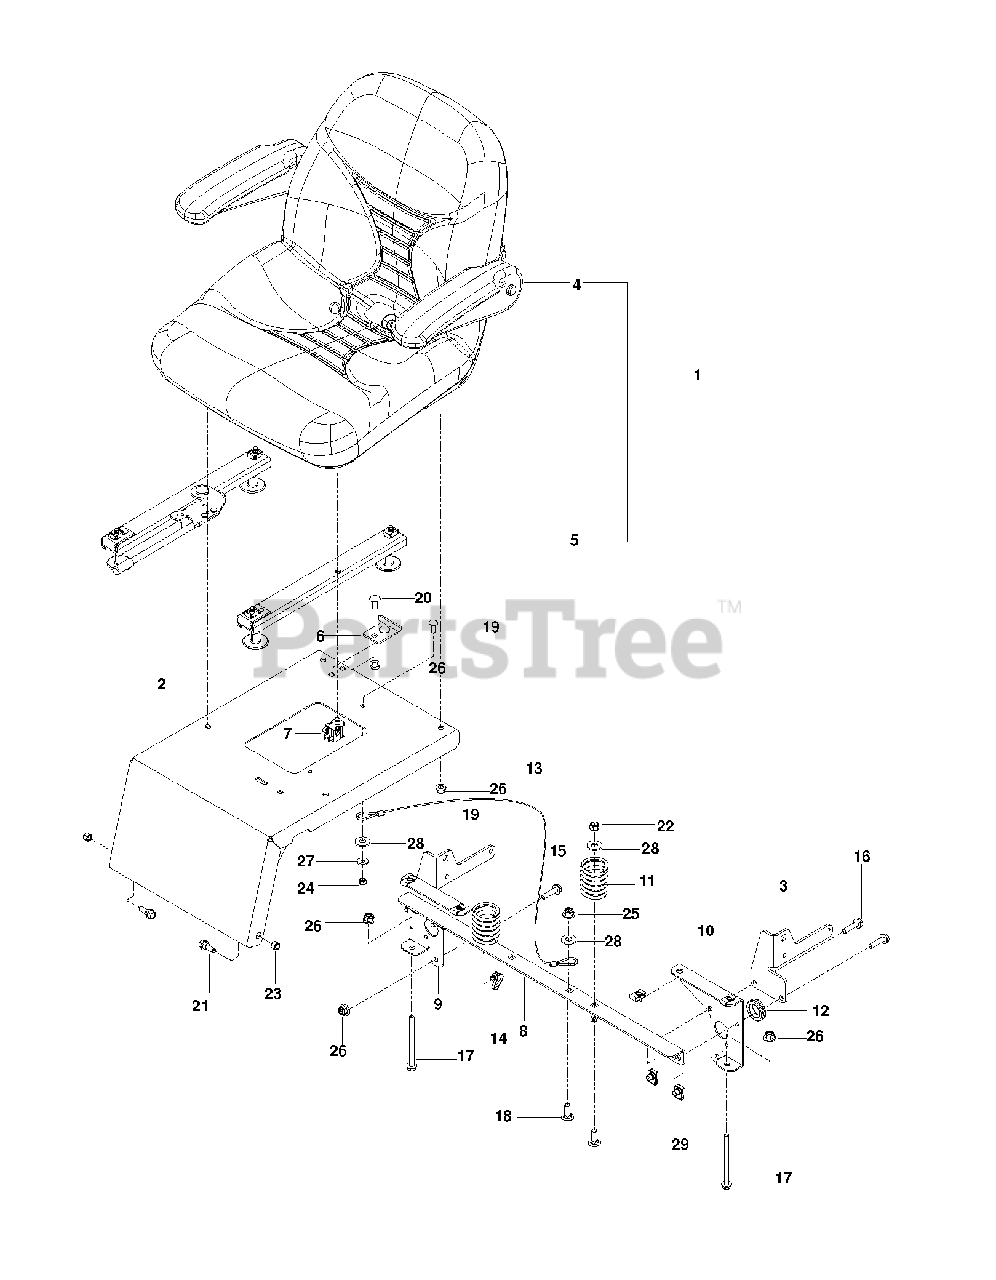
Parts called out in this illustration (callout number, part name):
1	SEAT
2	KIT.SEAT.MOUNT.W/DECAL
3	MOUNT, SEAT BELT, BLACK
4	ARMREST KIT, LT SQUARE END
5	TRACK ADJUSTMENT KIT
6	STOP, SEAT - BLACK
7	SEAT SWITCH
8	SUPPORT, SEAT
9	SUPPORT, RT, BLK
10	SUPPORT, LT, BLK
11	SPRING, SEAT
12	RUBBER GROMMET
13	SEAT LANYARD
14	TIE WRAP, 8-3/8", W/CLIP
15	HHFS 5/16-18 X 3/4
16	HHFS 5/16-18 X 1.25 TPBLT GD 5
17	HHFS 5/16-18 X 3 3/4
18	RHSNB 3/8C X 1
19	RHSNB 1/4C X 3/4
20	RHSNB 5/16-18 X 3/4
21	SB 5/16-18 HEX HD GD5, BLK ZN
22	NUT 3/8-16 NYLOC
23	NUT 5/16 NYLOC
24	RP_NUT 1/4-20 NYLOC
25	NUT 3/8-16 HEX FLG NYLOC ZD
26	5/16-18 NYLOC FLANGE NUT
27	WASHER 1/4 FLAT
28	RP WASHER 3/8 FLAT
29	U-CLIP 5/16-18 NUT RETAINER
